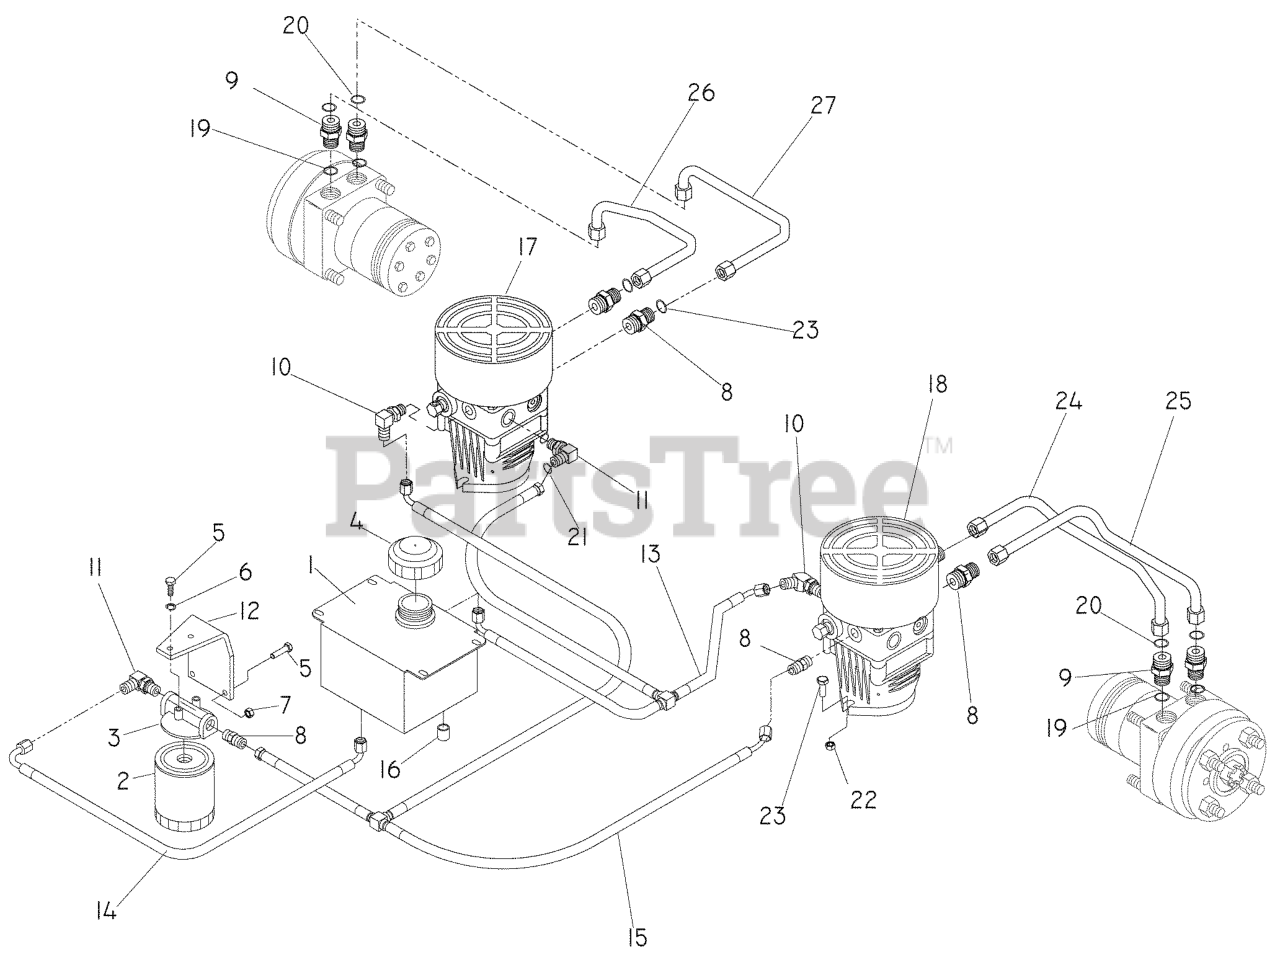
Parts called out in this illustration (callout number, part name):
2	HYDRAULIC OIL FILTER
3	FILTER HEAD
4	HYDRAULIC CAP
5	HCS 1/4C X 3/4 HCS
6	LOCKWASHER 1/4"
7	NUT.1/4-20.HEX.NYLOC.ZD
8	HYDRAULIC FITTING
10	45 DEG ADJ ELBOW
11	ELBOW, F6801-6-6-0 90 DEGREE
12	OIL FILTER BRKT
13	HOSE, T-ASM RETURN
14	HOSE, TANK - FILTER LINE
15	HOSE, T-ASM SUPPLY
16	NUT 9/16-18 JIC CAP
17	HG_PUMP, 10CC W/FAN RIGHT
18	HG_PUMP, 10CC W/FAN LEFT
22	NUT 3/8C CENTERBLOCK
23	4CS 3/8C X 1 SERRATED HEAD
24	HOSE, RPA - MA LINE
25	HOSE, RPB - MB LINE
26	HOSE, LPA - MB LINE
27	HOSE, LPB - MA LINE
